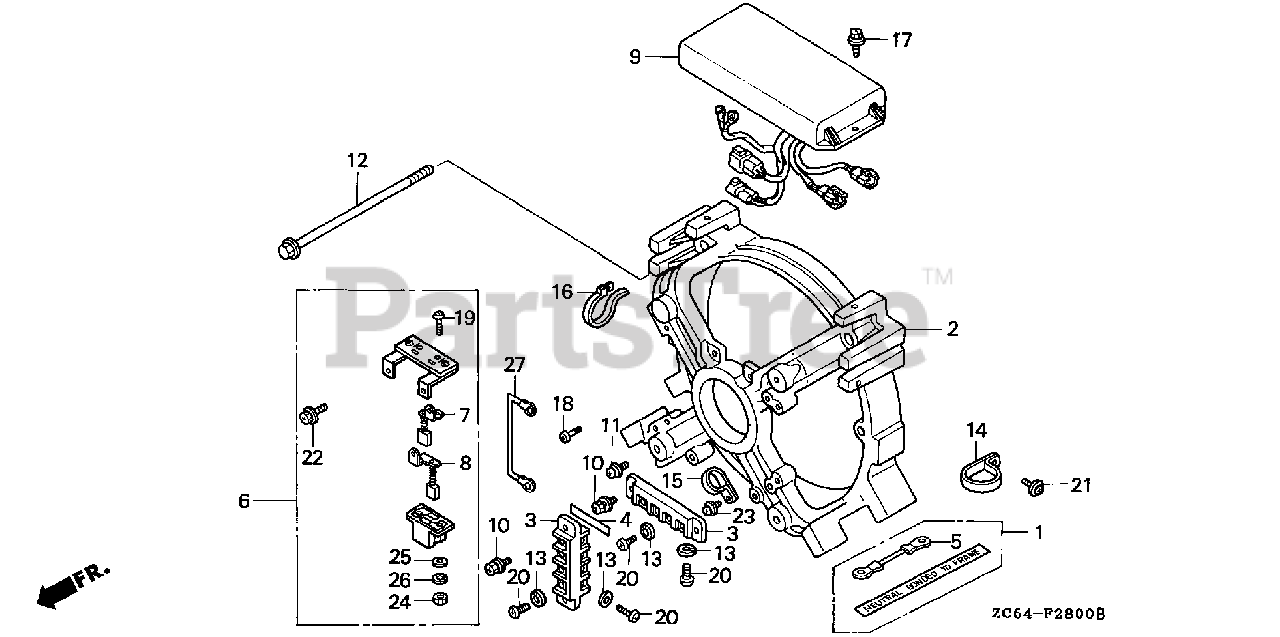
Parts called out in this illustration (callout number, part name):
1	CORD KIT, GROUND
2	HOUSING, RR.
3	TERMINAL, A.C. OUT
5	WIRE, GROUND
6	BRUSH ASSY.
9	REGULATOR ASSY., AUTOMATIC VOLTAGE
10	SCREW, TAPPING (5X18)
11	SCREW, PAN (5X12)
12	BOLT, FLANGE (10X170)
13	WASHER, SPRING (6MM)
15	CLIP (18.6MM) (A)
16	TIE, CABLE
17	BOLT-WASHER (6X20)
18	SCREW, PAN (4X8)
19	SCREW, PAN (4X16)
20	SCREW, PAN (6X8)
21	SCREW-WASHER (4X12)
22	SCREW-WASHER (5X12)
23	SCREW-WASHER (5X12)
24	NUT, HEX. (4MM)
25	WASHER, PLAIN (4MM)
26	WASHER, SPRING (4MM)
